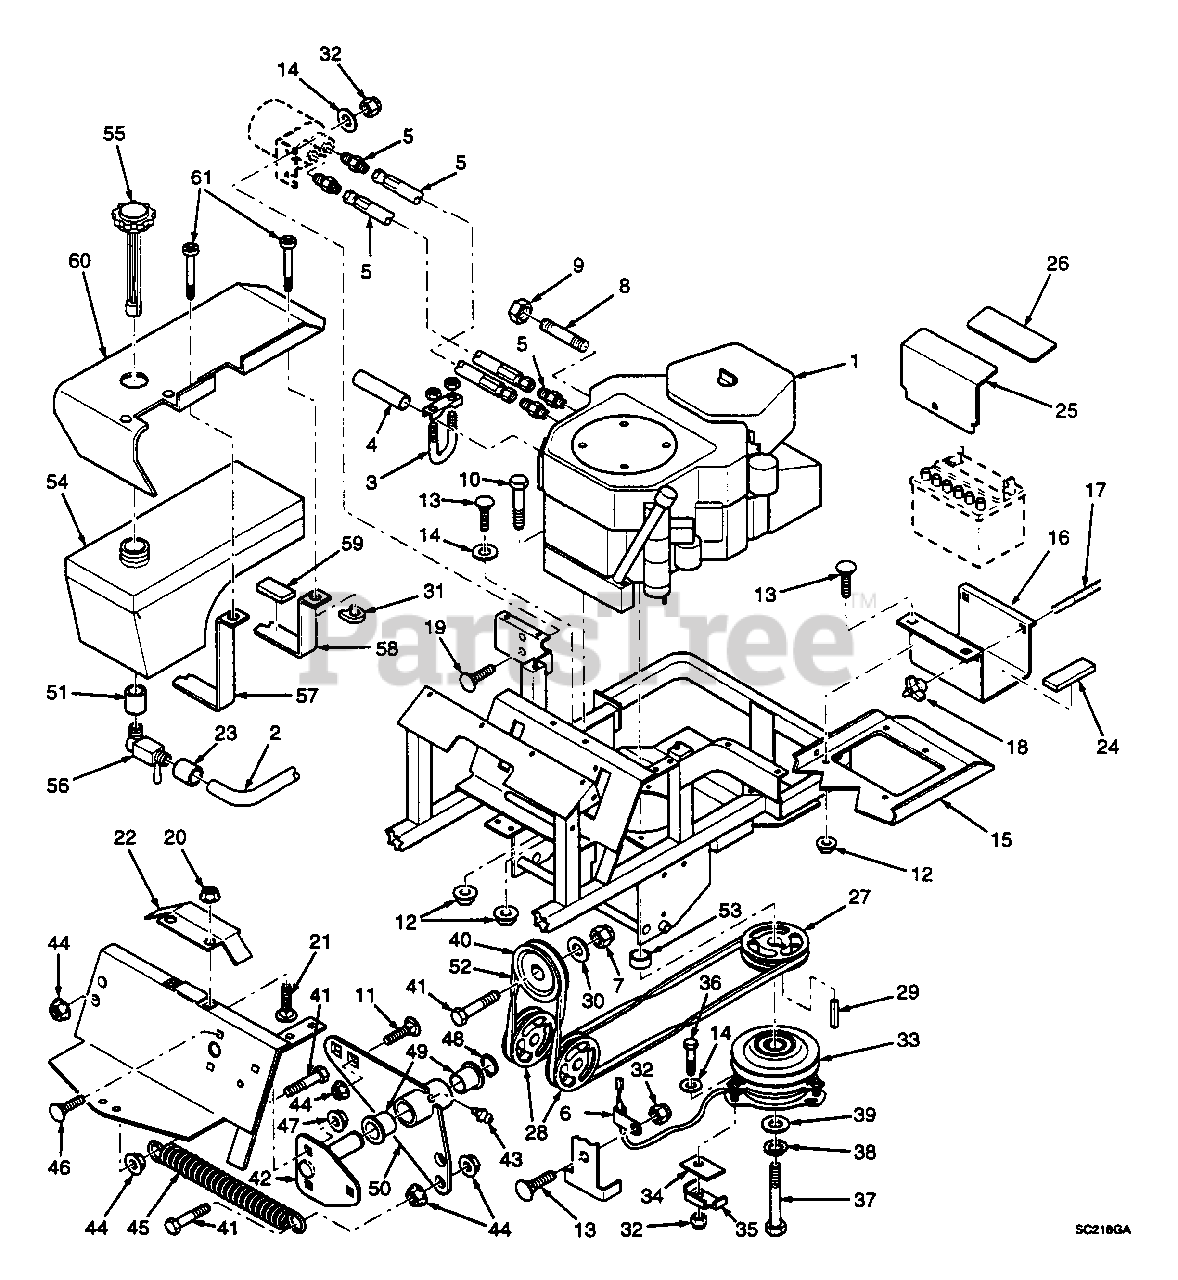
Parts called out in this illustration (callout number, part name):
1	Engine 20 hp Kohler CV For SSZ-20CV
2	Fuel Hose
3	Muffler Clamp
4	Tube, Exhaust
5	Kohler Fittings, Purchase From Kohler
6	Clamp, 50 ID
7	Nut, 3/8-16 Elastic Stop
8	Extention, 3"
9	Pipe Cap
10	Bolt, 5/16-18 x 1-1/2" Serr. Flng. Hex Head
11	Bolt, 70-16 x 1.50" Carriage
12	Nut, Serrated Range Hex Head 5/16-18
13	Bolt, Carriage 5/16-18 x 3/4"
14	Flatwasher, 5/16" (.313 x .875 x .083)
15	Fender, LH
16	Battery Box
17	Bolt, Carriage 1/4-20 x 6"
18	Wing Nut, 1/4-20
19	Bolt, Carriage 5/16-18 x 1"
20	Nut, Serrated Flange Hex 1/4-20
21	Bolt, Carriage 1/4-20 x 3/4"
22	Belt Guard
23	Fuel Hose Clamp
24	Rubber Pad
25	Battery Cover
26	Pad, Battery Cover
26	Pulley, Pump
27	Pulley
29	Key, 1/4 x 1/4 x 1-1/2
30	Flatwasher, 3/8 (.391 x.938 x.105)
31	U-Nut, 1/4-20
32	Nut, Elastic Stop 5/16-18
33	Electric Clutch
34	Rubber Pad, Clutch Stop
35	Backing Plate
36	Bolt, Hex Head 5/16-18 x 1-1/4
37	Bolt, Hex Head 7/16-20 x 2.50
38	Lockwasher, 7/16"
39	Flatwasher, 7/16" Special
40	Idler, Pulley
41	Bolt, Hex Head 3/8-16 x 1.75
42	Pivot Weldment, Idler Arm
43	Grease Fitting
44	Nut, Serrated Flange Hex 3/8-16
45	Spring, Pump Drive Idler
46	Bolt, Carriage 5/16-18 x 3/4
47	Nut, Serrated Flange Hex 5/16-18
48	Ring, Retaining 1.125 Diameter External "E"
49	Bushing, 1.125 Sintered
50	Idler Arm Weldment, Pump Drive
51	Bushing, Fuel Tank Valve
52	Belt, Pump Drive
53	Spacer, Crankshaft
54	Fuel Tank
55	Fuel Tank Cap
56	Fuel Shut-off Valve
57	Fuel Tank Strap, Long
58	Fuel Tank Strap, Short
59	Rubber Pad
60	Fender Assembly, RH
61	Screw, Machine 1/4-20 x 2" Phillips Head
62	Bolt, 5/16-18 x 1-1/2 Serr. Flng. Hex Head
63	Bolt, Carriage 7/8-16 x 1.50"
64	Nut, Elastic Stop 3/8-16
65	Clamp, .50 ID
66	Kohler Fittings, Purchase From Kohler
